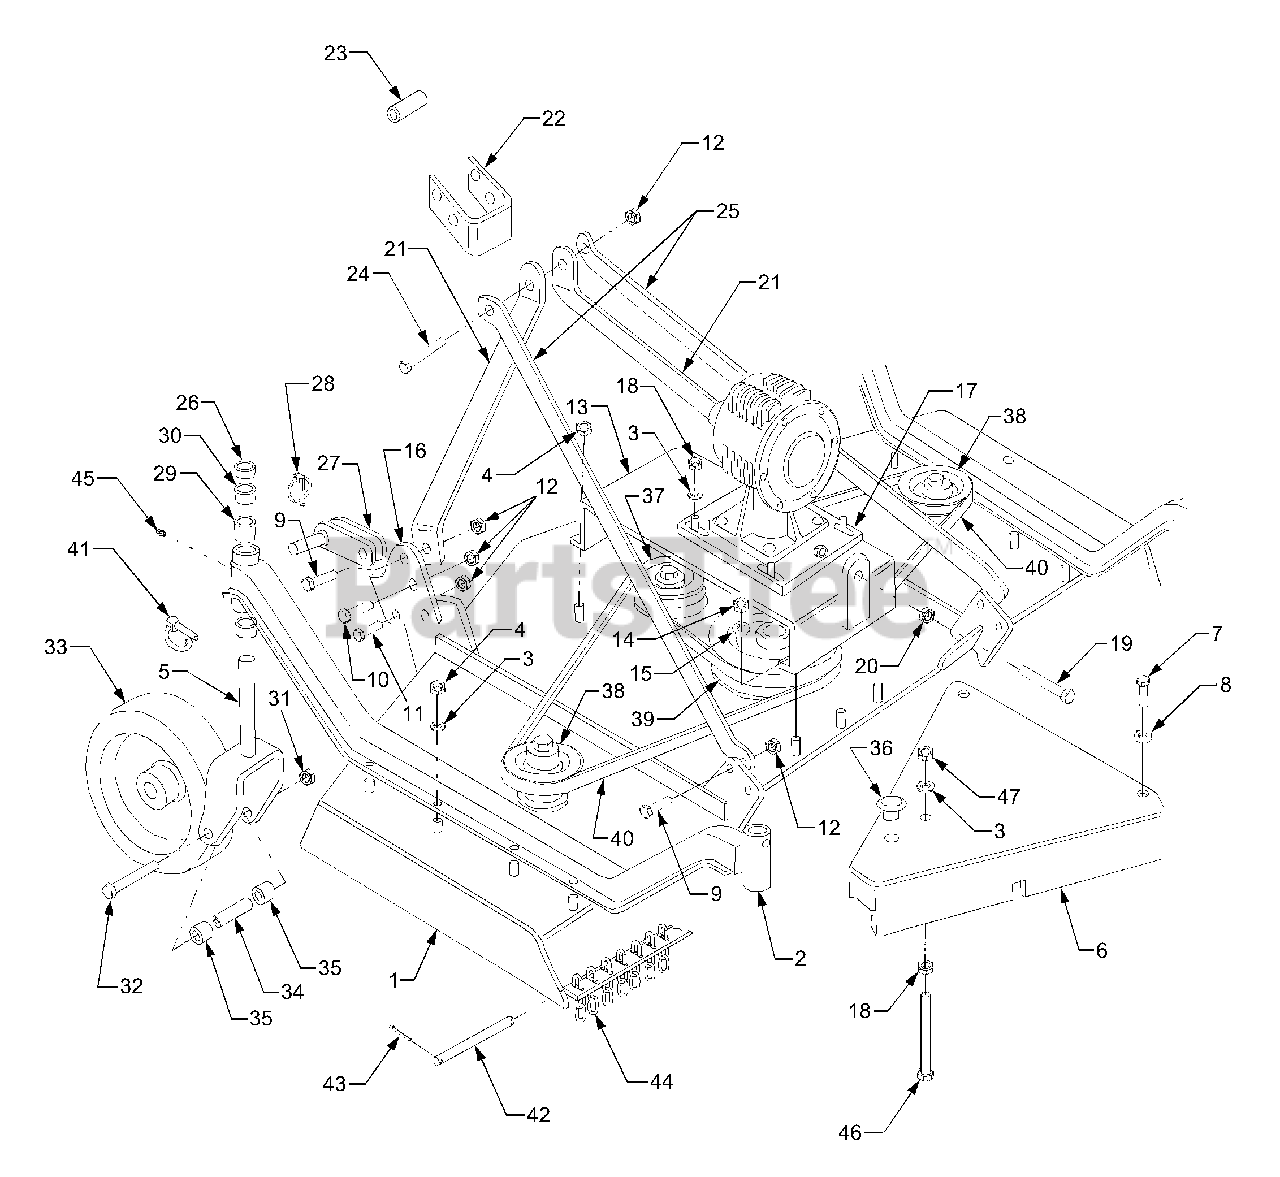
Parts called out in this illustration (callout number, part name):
3	Flat Washer, 10mm
6	Belt Shield
7	Bolt, 10 x 25
8	Flat Washer, 10mm
9	Bolt, 16 x 45
10	Bolt, 16 x 55
11	Bolt, 16 x 50
13	Central Plate
15	Lock Washer, 10mm
16	Lower Hitch Block Plate
17	Gearbox Flange
19	Bolt, 12 x 100
21	Top Hitch Support
22	Top Hitch Plate
24	Bolt, 16 x 150
25	Top Hitch Arm
26	1/4" Height Adjustment Spacer
27	Hitch Block
30	1/2" Spacer
32	Bolt, 14 x 150
34	Inner Bushing
35	Outer Spacer
36	Plastic Cap
41	Locking Pin
45	Grease Fitting
46	Bolt, 10 x 120
